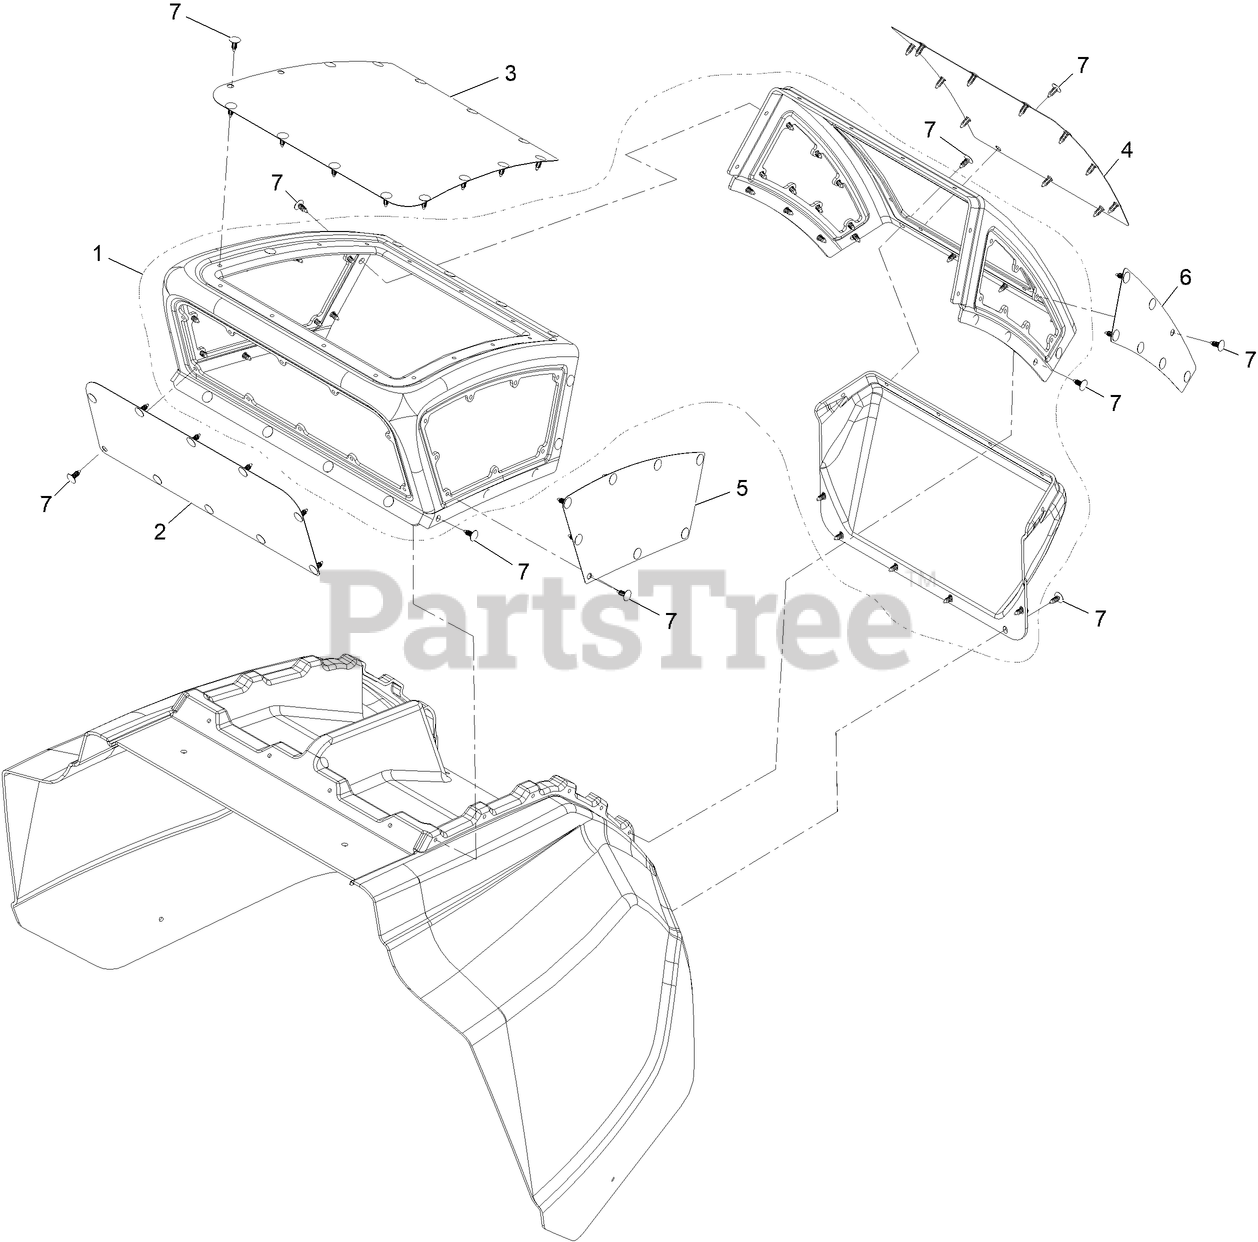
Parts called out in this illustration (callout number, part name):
1	HOOD-INTAKE
2	Screen-Intake [black]
3	Screen-Intake [black]
4	Screen-Intake [black]
5	Screen-Intake [black]
6	Screen-Intake [black]
7	PLUG-PLASTIC
